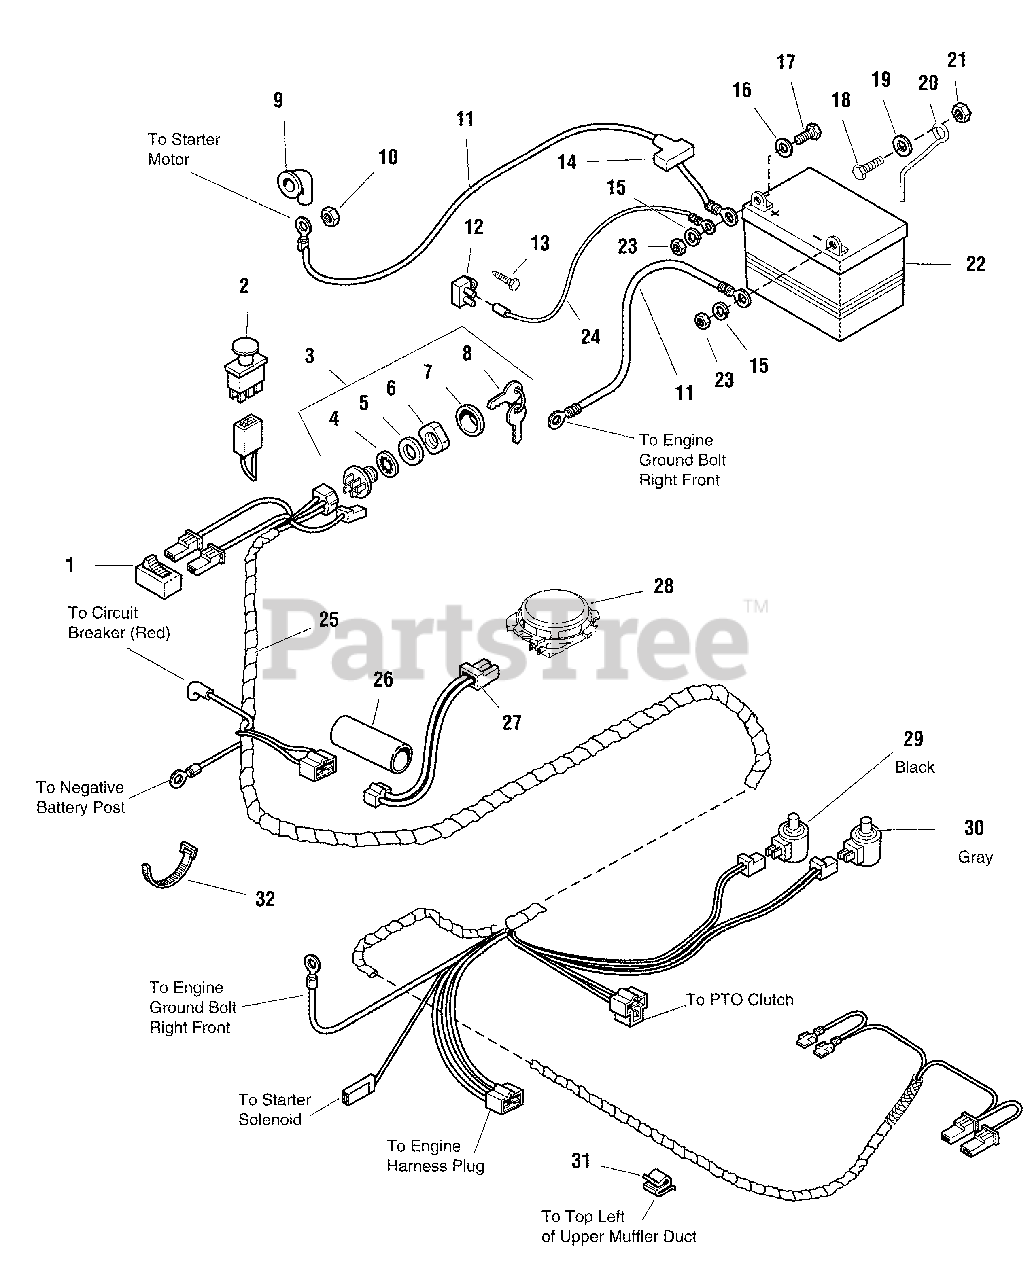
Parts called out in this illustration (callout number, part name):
1	SWITCH, Rocker, Headlight
2	SWITCH, PTO, Push Pull
3	SWITCH ASSEMBLY, Ignition (Includes Ref. Nos. 4, 5, 6, 7 & 8)
4	LOCKWASHER, Internal Tooth
6	NUT, Hex Flange, 5/8-32
7	COVER, Ignition Switch
8	KEY, Ignition
9	BOOT, Insulator
10	NUT, Hex Flange, 8MM x 1.25, Yellow
11	CABLE, # 6 x 52-1/2" Long
12	BREAKER, Circuit, 12 Volt 20 Amps
13	SCREW, Hex Head, Taptite, 1/4-20 x 5/8
14	BOOT, Insulator, Battery Terminal
15	LOCKWASHER
16	WASHER
17	CAPSCREW, Hex Head, 1/4-20 x 3/4
18	CAPSCREW, Hex Head, 5/16 x 18 x 3/4
20	ROD, Battery Hold Down
21	NUT, Hex Lock ESNA, 5/16-18
22	BATTERY, 12 Volt
23	NUT, Hex, 1/4-20
24	WIRE, #12 x 11" Long
25	HARNESS, Wiring, For Honda Engines with 6 Pin Engine Connector
25	HARNESS, Wiring, For Honda Engines with out 6 Pin Engine Connector
26	SHRINK TUBE, 3" Long
27	WIRE ASSEMBLY
28	SWITCH, Seat, Gray Switch, Gray Retainer
28	SWITCH, Seat, Gray Switch, Black Retainer
29	SWITCH, NO, Black, Push Button W/Boot
30	SWITCH, NC, Gray, Push Button, W/Boot
31	CLIP, Wire
32	TIE, Self Locking
33	CABLE, Red, # 6 x 52-1/2" Long
34	TAG, Battery Charge, Warranty
